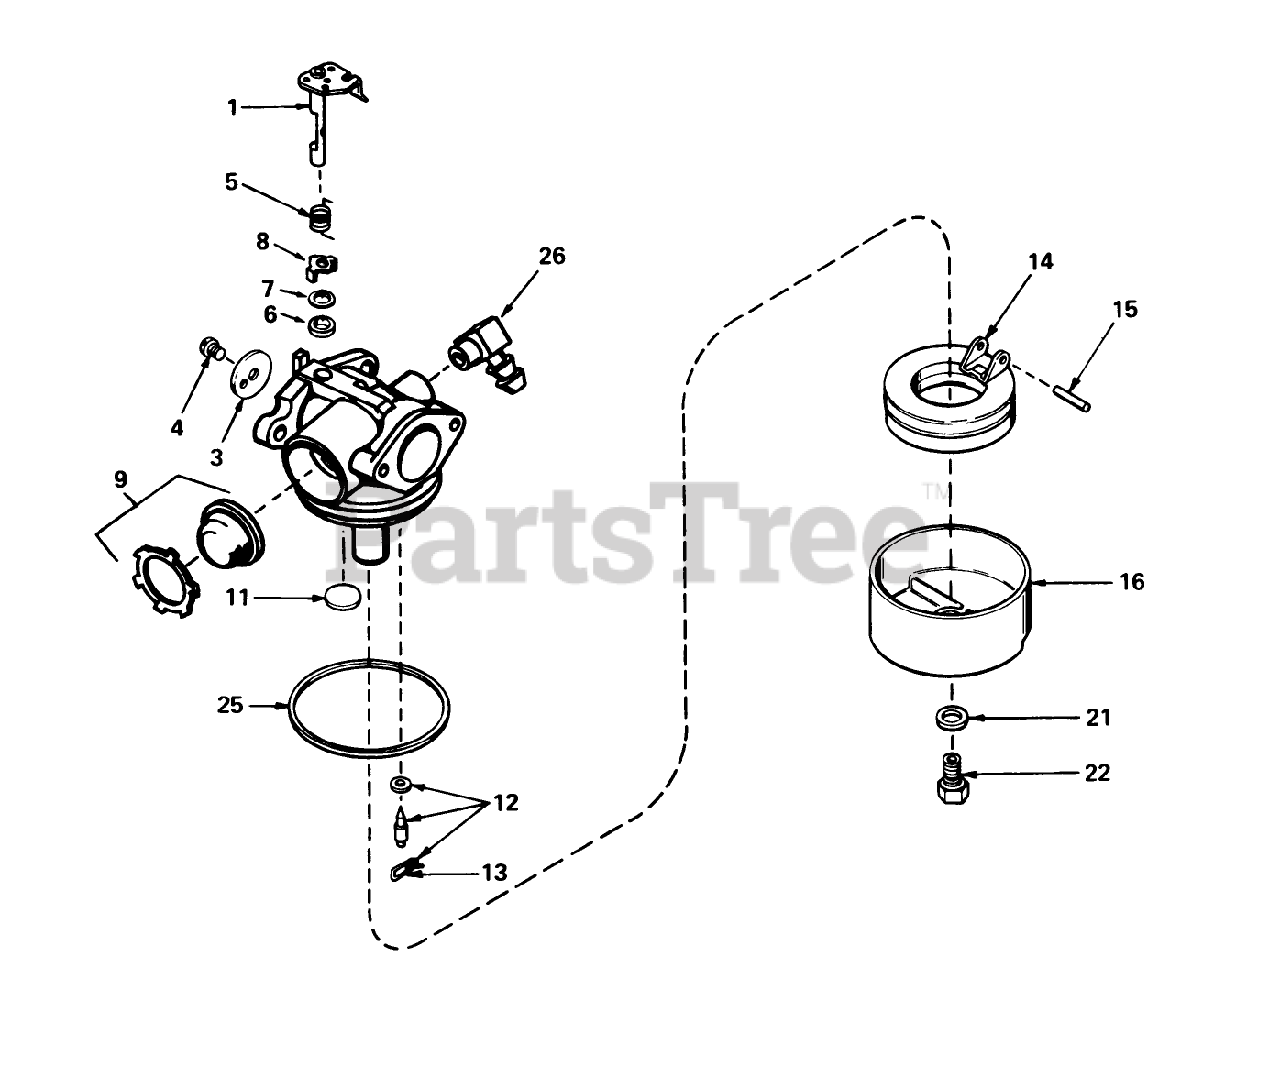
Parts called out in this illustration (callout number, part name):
1	Throttle Shaft and Lever ASM
3	Throttle-Shutter
4	Screw-Shutter
5	Spring, Return
6	Seal-Dust
7	Washer-Seal, Dust
8	Retainer, Seal
9	Primer Assy.
11	Plug-Welch, Atmospheric Vent
12	Inlet Needle, Seat Clip Assy. (Incl. No. 13)
13	Clip-Spring
14	Float
15	Shaft-Float
16	Bowl Float
21	Gasket-Bowl
22	Nut-Float Bowl
25	O Ring-Bowl, Float
26	Fitting-Fuel
